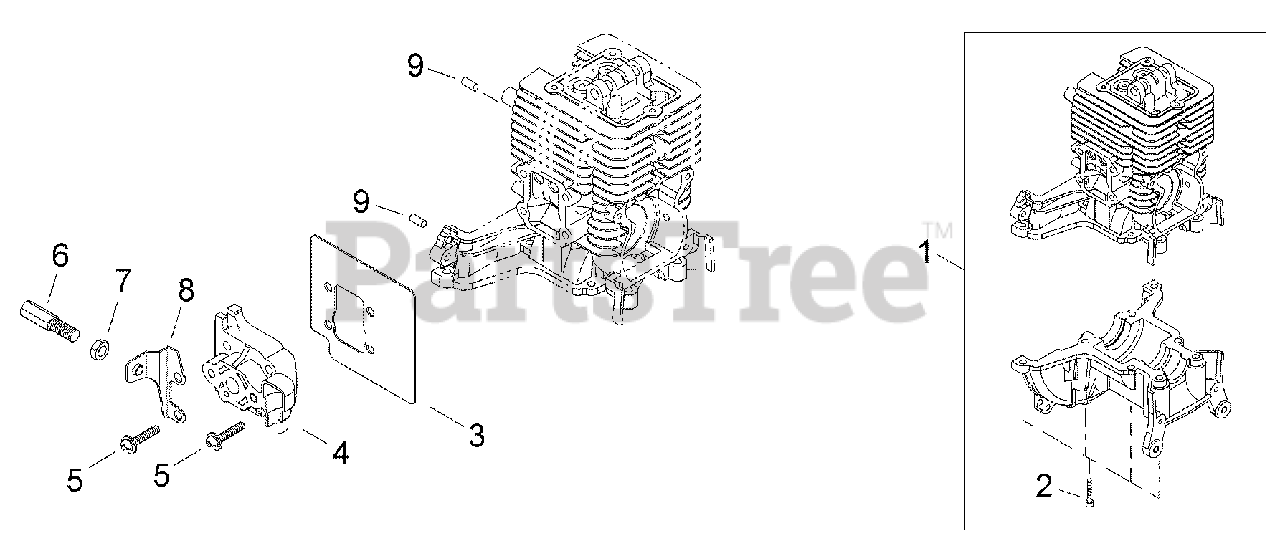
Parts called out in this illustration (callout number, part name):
1	CYLINDER & CRANKCASE ASSY
2	BOLT 5×16
3	HEAT SHIELD, INTAKE
4	INSULATOR WITH REED VALVE
5	SCREW M5×25
6	ADJUSTER, THROTTLE CABLE
7	NUT, ADJUSTER LOCK M6
8	BRACKET, THROTTLE CABLE
9	PIN, LOCATING Ø4×8
